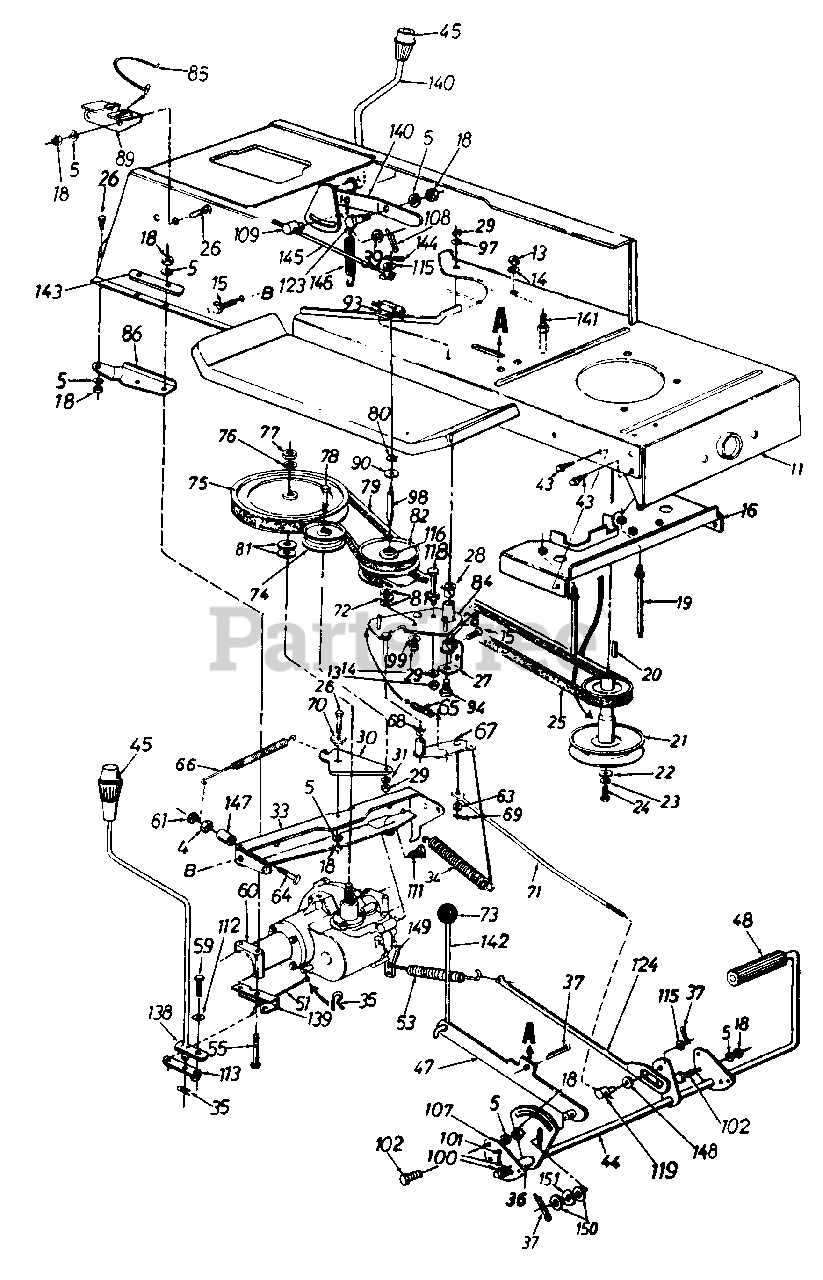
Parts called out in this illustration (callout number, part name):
4	Hex Nut 5/16-24 Thd.
5	L-Wash. 5/16" I.D.
14	L-Wash 1/4" I.D.
15	Hex Wash TT-Tap Scr. 5/16-18 x .62" Lg.
18	Hex Nut 5/16-18 Thd.
19	Belt Guard Stud 3.6" Lg.
20	Sq. Key 1/4" x 1/4" x 2.00"
21	Engine Pulley
22	Fl-Wash. 7/16" I.D. x 1.25"
23	L-Wash. 7/16" I.D.
24	Hex Bolt 7/16-20 x 1.50" Lg.
25	Variable-Speed Belt
26	Hex Bolt 5/16-18 x .75" Lg.
27	Bearing Shaft Bracket
28	Flanged Nyliner Brg. .63" I.D. x .6" Lg.
29	Hex Nut 3/8-24 Thd.
30	Idler Bracket
31	L-Wash. 3/8" I.D.
33	Transaxle Support Brkt.
34	Ext. Spring .94" O.D. x 7.58"
35	Inter. Cotter Pin
36	Spacer .63" I D.
37	Cotter Pin 1/8" Dia. x 1.25" Lg.
39	Fl-Wash .51" I.D. x .75"
44	Clutch/Brake Pedal Ass'y.
45	Shift Knob
47	Parking Brake Lockout Brkt. Ass'y.
48	Foot Pad
51	Shift Lever Rod
53	Ext. Spring 3.6"
55	Hex Bolt 5/16-18 x 3.25"
59	Hex Bolt 1/4-28 x .62" Lg.
60	Transaxle Complete
61	Hex L-Nut 1/4-20 Thd.
63	Fl-Wash. .34" I.D. x .68" O.D.
64	Hex Wash. TT-Tap Scr. 1/4-20 x 1.75"
65	Ext. Spring 2.59" Lg,
66	Ext. Spring .5" O.D. x 4.35"
68	Flanged Bearing
69	Cotter Pin 3/32" Dia.
70	Shoulder Spacer .27" Lg.
71	Speed Control Link
72	Truss Bearing .56 Dia. x 1.25"
73	Ball Knob
74	Fl-Idler Pulley 3.25" x 75"
75	"V"-Pulley
76	Bell-Wash. .567" I.D. x 1 125"
77	Hex Jam Nut 9/16-18 Thd.
78	Hex Bolt 3/8-24 x 1.75" Lg.
79	Variable Speed Belt
80	Snap Ring .56" Dia.
81	Fl-Wash. .56" I.D. x 1.0" O.D.
82	Variable Speed Pulley Ass'y. 5" O.D.
84	Variable Speed Brkt. Ass'y.
85	Comp. Spring - Clip
90	Teflon Washer .565" I.D.
93	Safety Switch (Clutch)
94	Shld. Bolt 3/8-24 x 3.12" Lg.
97	Bell-Wash. .38" I.D. x .88"
98	Shaft
99	Bell-Wash. .39" I.D. x 1.12"
100	Fl-Wash. .64" I.D. x .94"
101	Cotter Pin 1/8" Dia. x 1.25"
102	Hex Wash. Hd. Scr. 5/16-18 x .62" Lg.
109	Ferrule
111	Hex Wash. Tap Scr.
112	Bell-Wash. .265" I.D. x .75"
113	Shift Lever Link Ass'y.
115	Fl-Wash .385" I.D. x .62"
116	Needle Brgs.
118	Belt Keeper 3" Lg.
119	Ferrule
123	Shld. Bolt .437" Dia. x .162"
124	Brake Rod Ass'y.
138	Shift Lever Ass'y.
139	Shift Lever Support Brkt.
140	Speed Selector Lever Ass'y.
141	Belt Guard Pin
142	Brake Lockout Rod
144	Cotter Pin 1/8" x 3/4" Lg.
145	Speed Selector Rod
146	Ext. Spring 3.97" Lg.
147	Spacer .326" I.D. x .47"
148	Fl-Wash. 5/8" I.D. x 1.25"
149	Actuating Arm
150	Fl-Wash. .385" I.D. x .87" O.D.
151	Wave Wash. .38" I.D. x .75"
